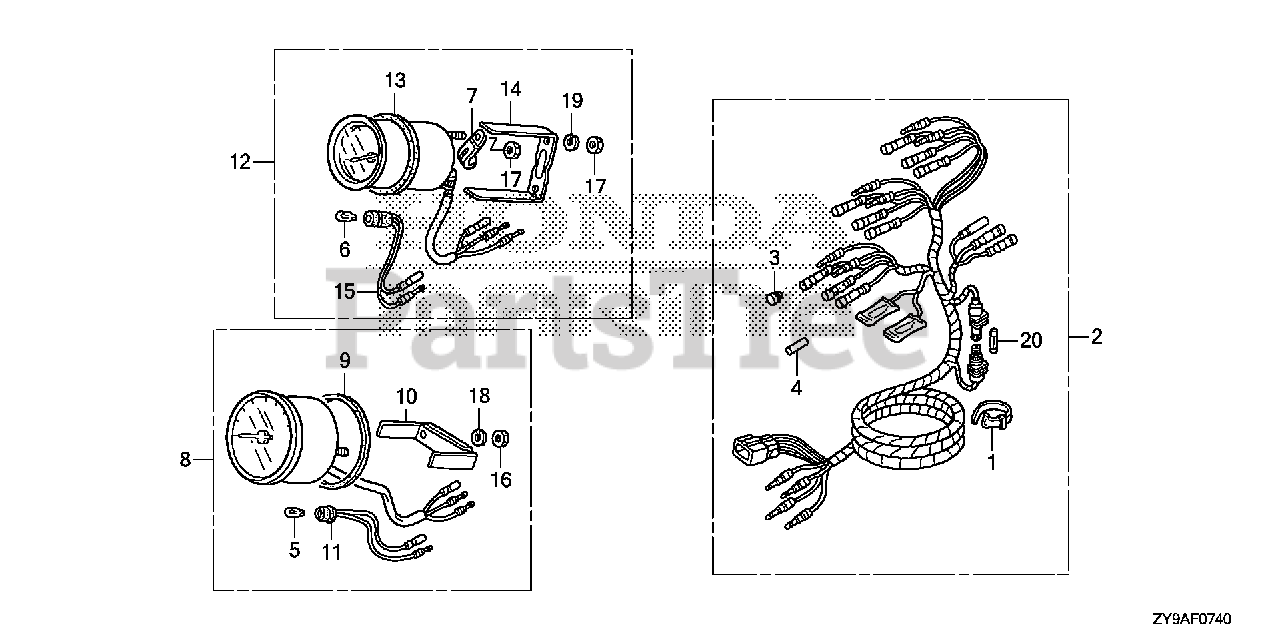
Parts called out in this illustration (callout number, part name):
1	BAND B1, WIRE
2	HARNESS ASSY., METER (A)
3	PLUG, CONNECTOR (INNER)
4	PLUG, CONNECTOR (OUTER)
5	BULB, WEDGE BASE (T10) (12V 1.7W) (STANLEY)
6	BULB, WEDGE BASE (12V 1.7W)
7	CLAMP
8	TACHOMETER ASSY.
9	GASKET
10	BRACKET
11	SOCKET
12	METER ASSY., TRIM
13	GASKET
14	BRACKET
15	SOCKET
16	NUT, HEX. (5MM)
17	NUT, HEX. (4MM)
18	WASHER, SPRING (5MM)
19	WASHER, SPRING (4MM)
20	FUSE A (10A)
